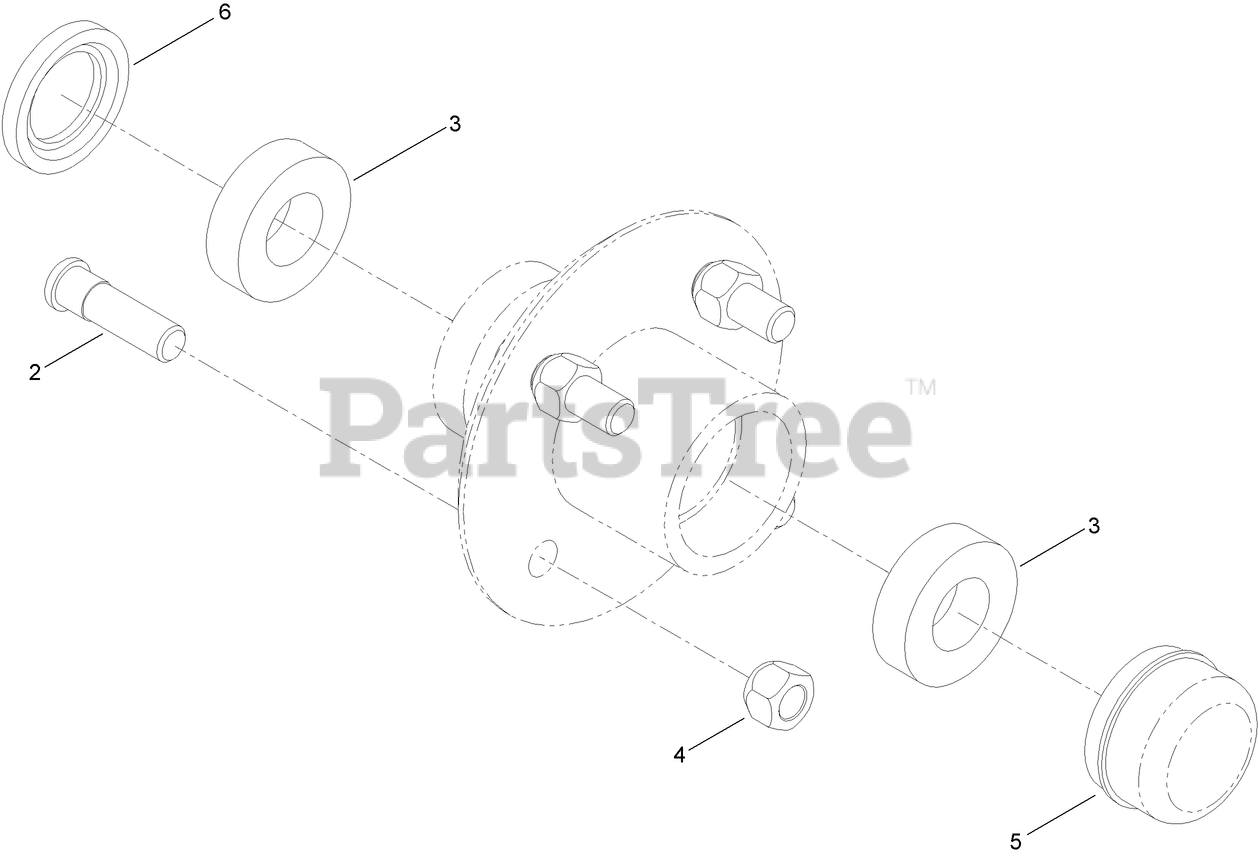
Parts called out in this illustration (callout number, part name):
2	STUD-WHEEL
3	BEARING-ROLLER
4	NUT-LUG
5	CAP-DUST
6	SEAL-HUB, WHEEL
